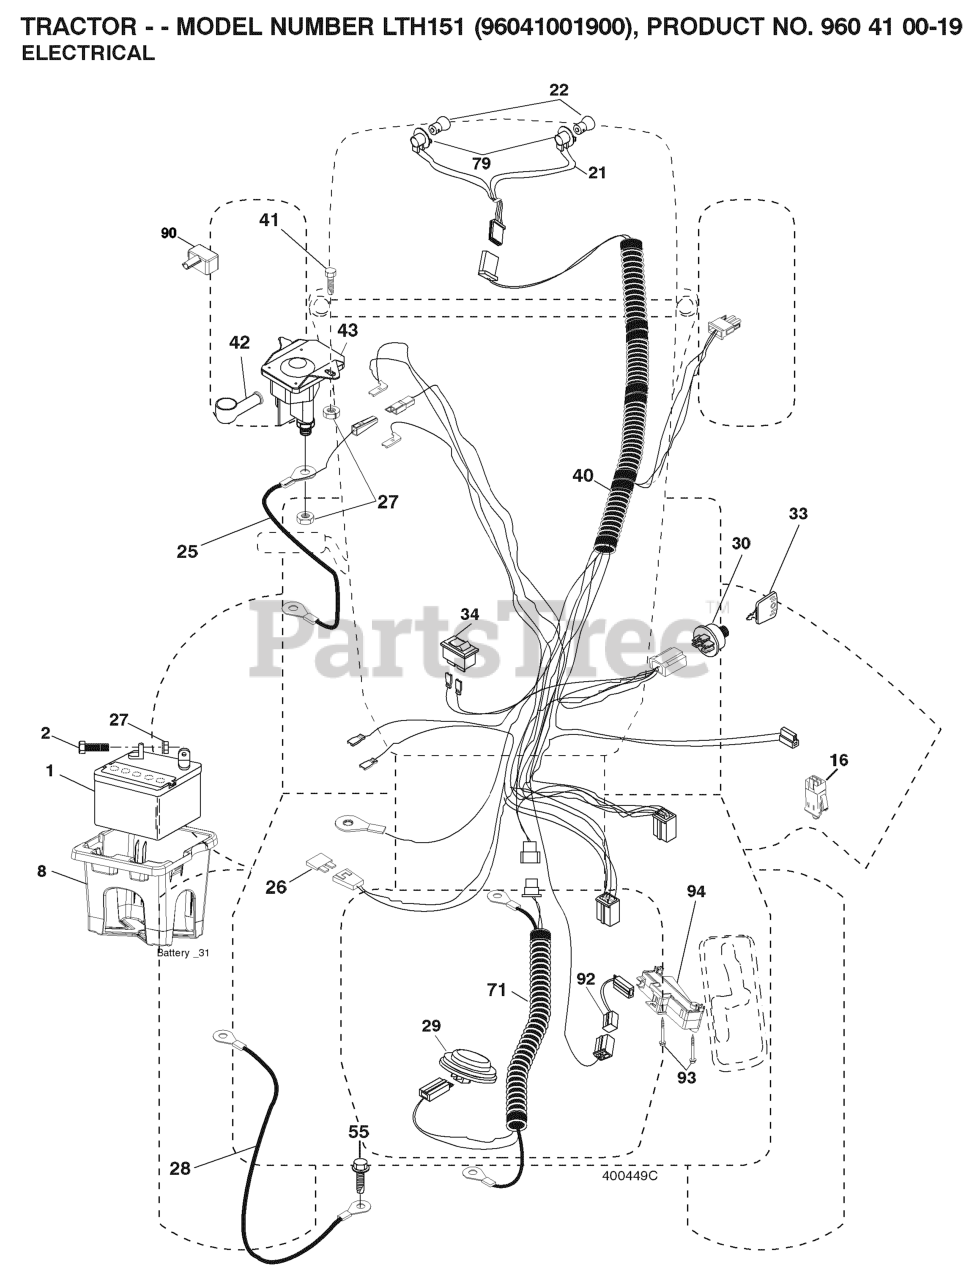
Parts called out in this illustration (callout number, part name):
1	BATTERY 12V .35 AMP
2	BOLT.HEX.1/4.X.3/4.DICHROMATE
8	BOX.BATTERY.MNT.REAR.L
16	SWITCH INTERLOOK PUSH-IN
21	HARNESS.LIGHT W/4152J BULBS
25	CABLE.STARTER.6GA.RED.
26	FUSE 20AMP
27	NUT
28	CABLE.BLACK.18"REAR.BA
29	SWITCH.SEAT.DELTA.OPC.
30	SWITCH.IGN.DELTA.W.LGH.ROS
33	KEY MLD GEN DELTA
40	HARNESS IGN. DASH
41	SCREW
42	TERMINAL COVER
43	SOLENOID.W/BRASS.PLUNGER
55	SCREW 5/16"
71	HARNESS.IGN.CHASS.TEX.REAR.BAT
79	BULB HOLDER ASM.
90	COVER, TERMINAL BATTERY
92	HARNESS.PIGTAIL.CONSLE
93	SCREW.PLASTITE
94	MODULE.REVERSE.ROS
